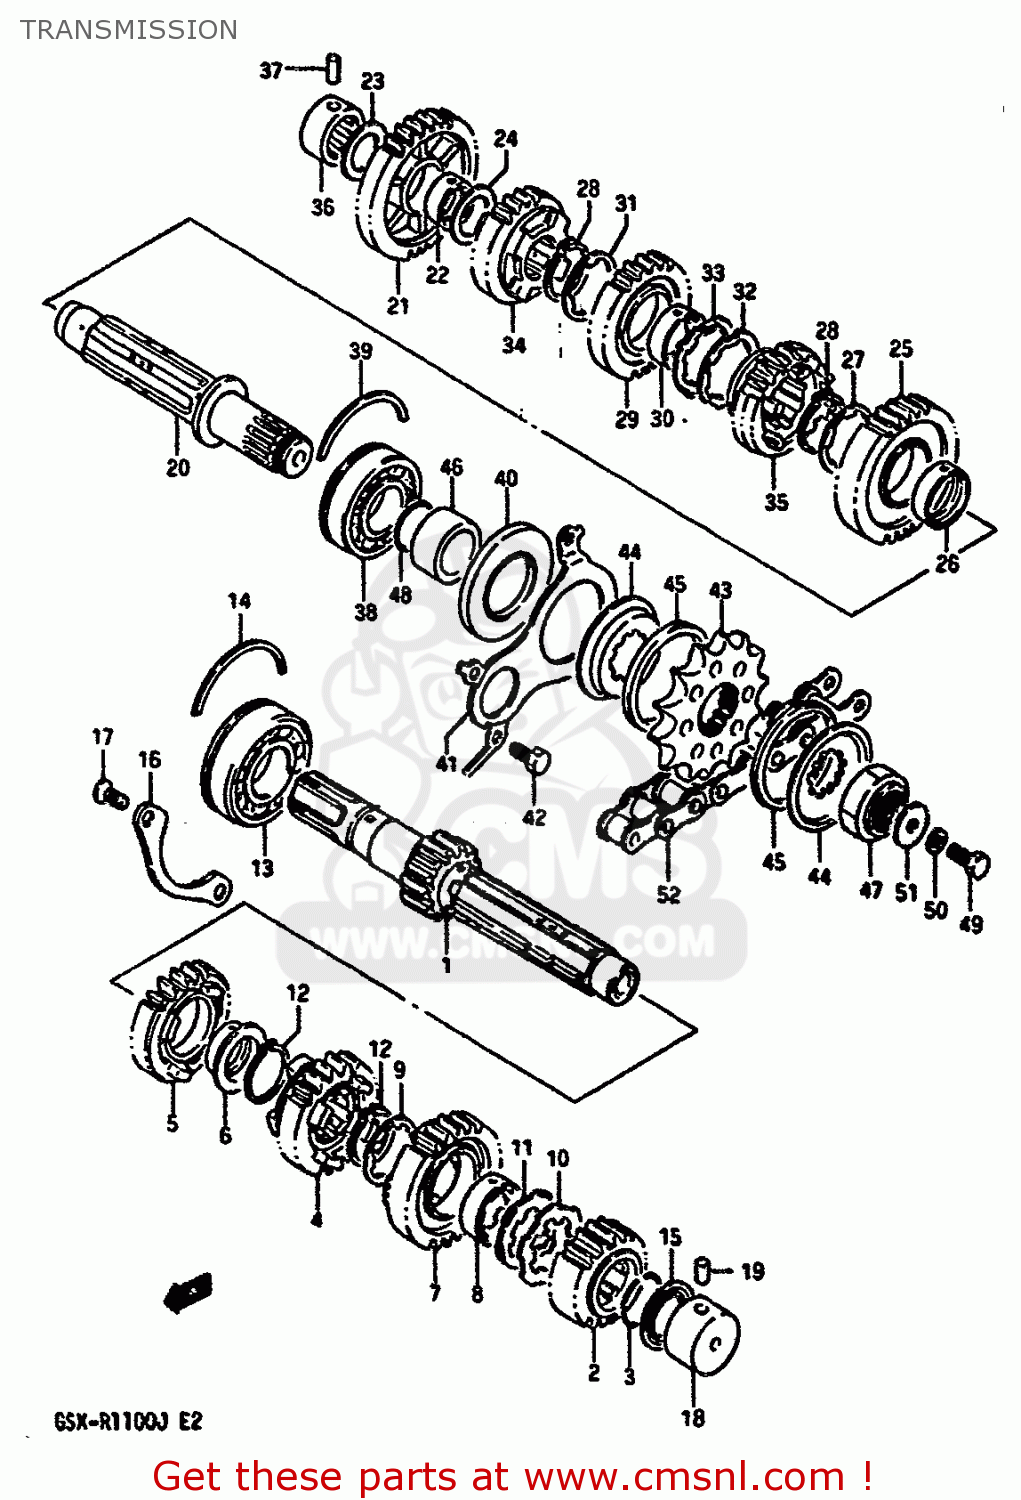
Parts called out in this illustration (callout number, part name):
1	SHAFT,COUNTER
2	GEAR,SECOND DRIVE
3	RING,SNAP
4	GEAR,THIRD DRIVE
5	GEAR,FOURTH DRIVE
6	BUSHING
7	GEAR,FIFTH DRIVE
8	BUSHING
9	WASHER,LOCK
10	WASHER,LOCK
11	WASHER
12	RING,SNAP
13	BEARING(25X62X17)
14	C-RING
15	SEAL,OIL(20X31.2X2.7)
16	RETAINER,CNTR SHAFT BEARING
17	SCREW
18	BEARING(20X34X17.5)
19	PIN
20	DRIVESHAFT
21	GEAR,FIRST DRIVEN
22	BUSHING
23	WASHER
24	WASHER
25	GEAR,2ND DRIVEN
26	BUSH(28X32X11)
27	WASHER
28	CIRCLIP
29	GEAR,THIRD DRIVEN
30	BUSH
31	WASHER,LOCK
32	WASHER,LOCK
33	WASHER
34	GEAR,FOURTH DRIVEN (NT:23)
35	GEAR,5TH DRIVEN
36	BEARING(20X34X20)
37	PIN
38	BEARING
39	C-RING
40	SEAL,OIL(34X62X6)
41	RETAINER,DRIVESHAFT O
42	BOLT
43	SPROCKET,ENGINE
44	HOLDER,SPROCKET DAMPER
45	DAMPER,ENGINE SPROCKET
46	SPACER (25X34X18.1)
47	NUT
48	O RING(D:1,ID:24.5)
49	BOLT
50	WASHER,LOCK
51	WASHER
52	CHAIN ASSEMBLY,DRIVE
